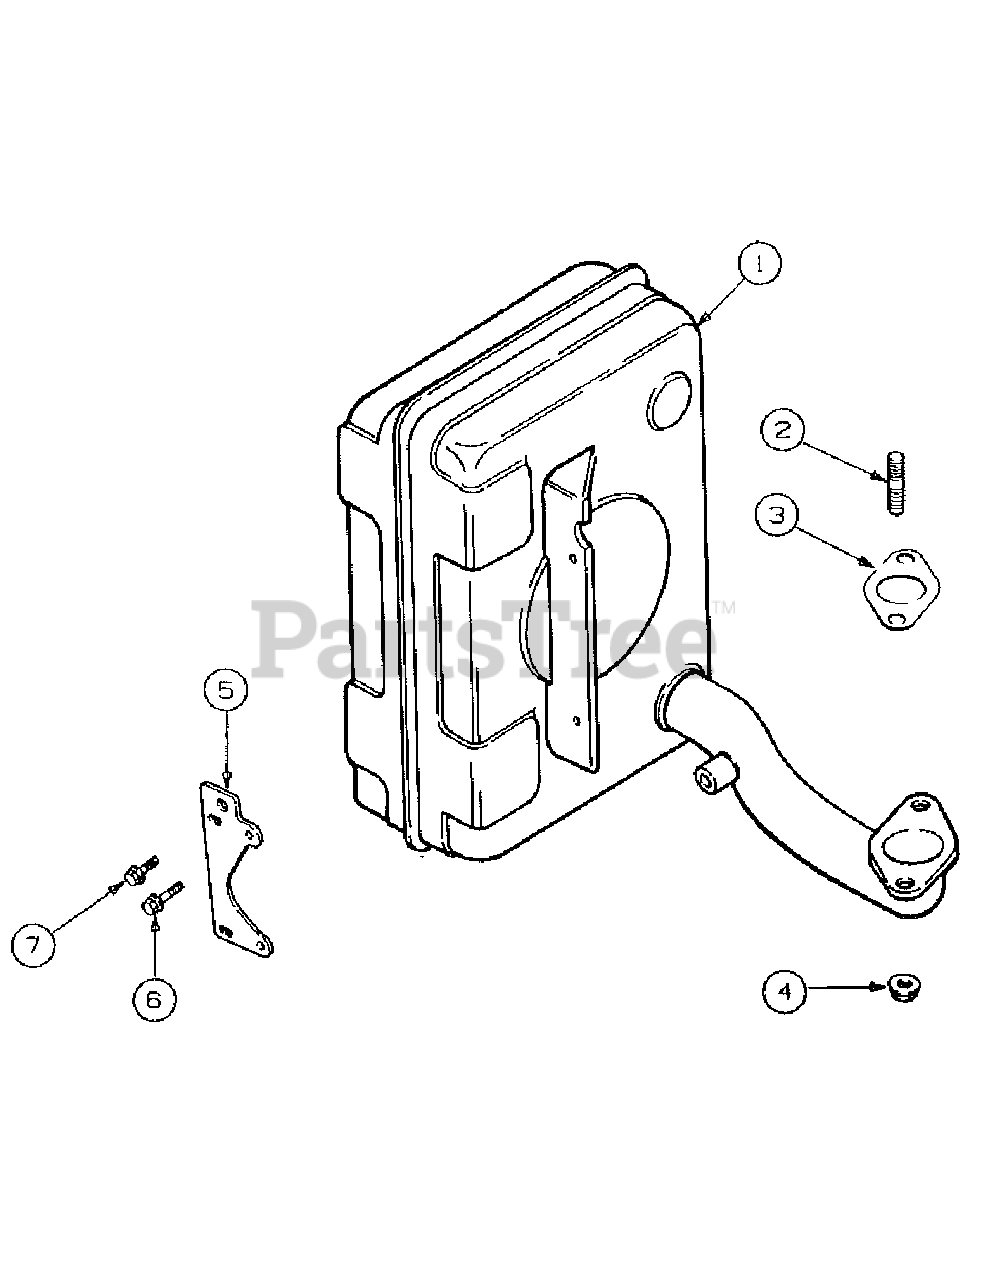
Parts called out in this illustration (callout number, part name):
2	Stud, Exhaust Manifold, M8 x 1.25 x 20
3	Gasket, Exhaust Manifold
4	Nut, Muffler, M8 x 1.25
5	Bracket, Muffler
6	Screw, Muffler Bracket
7	Screw, ValveCover
